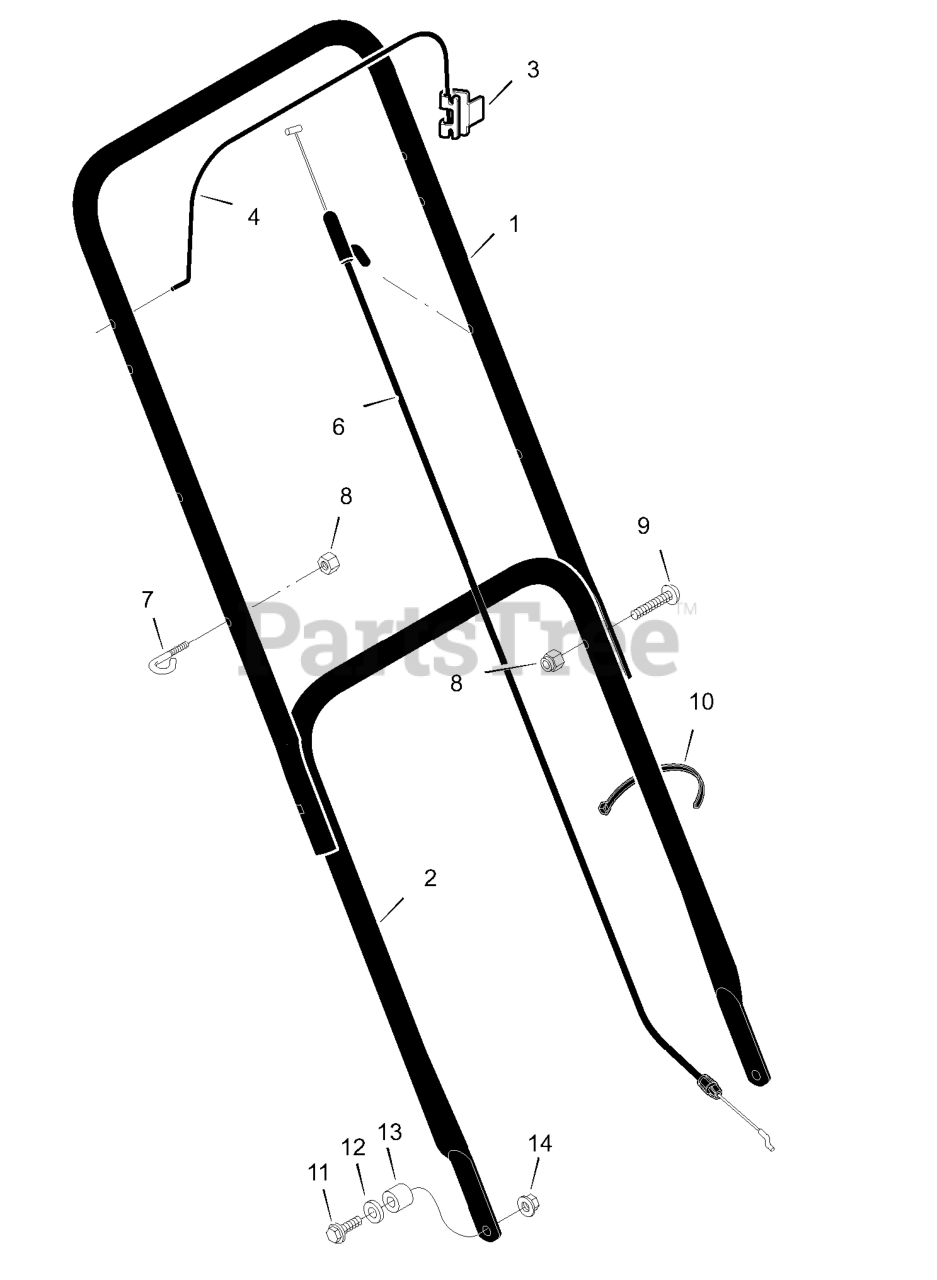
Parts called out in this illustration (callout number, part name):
1	Handle, Upper (Black)
2	Handle, Lower (Black)
3	Bracket, Stop Lever
4	Lever, Stop
6	Engine Stop Cable
7	GUIDE, ROPE
8	Locknut
10	Fastener, Cable
11	Bolt
14	Nut
